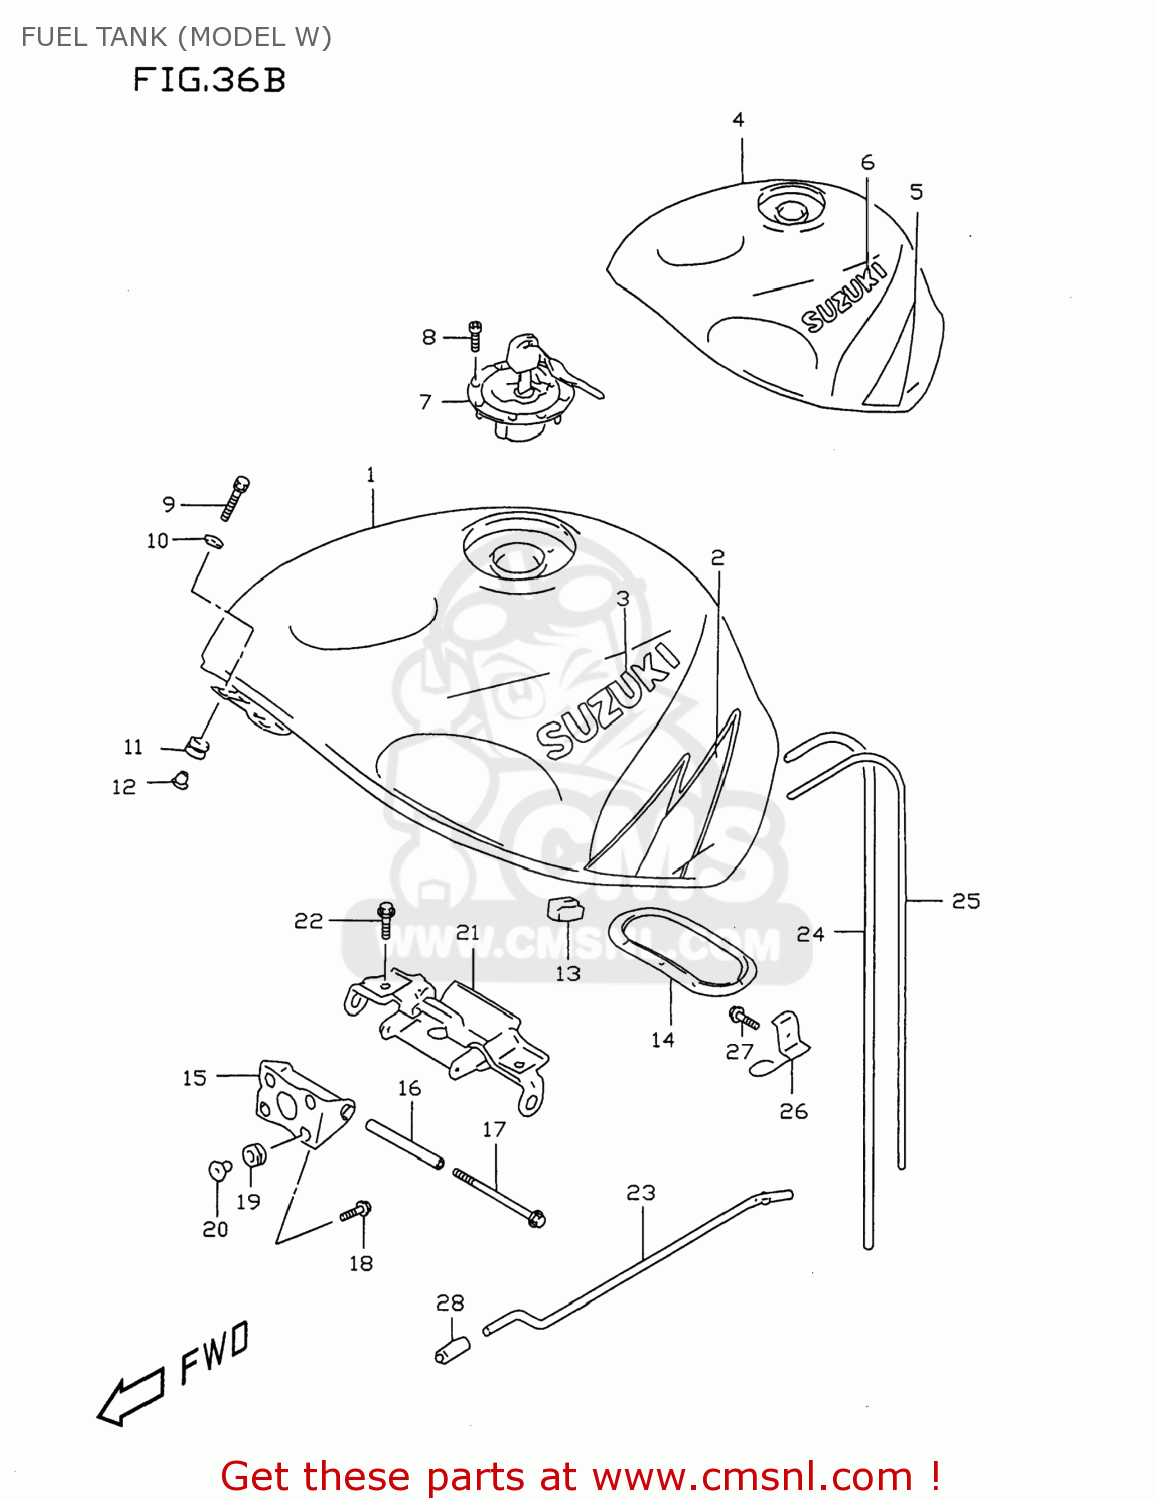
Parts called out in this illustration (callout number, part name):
1	TANK ASSEMBLY,FUEL
2	TAPE SET,FUEL TANK
3	EMBLEM,FUEL TANK
4	TANK ASSY,FUEL
5	TAPE SET,FUEL TANK
6	EMBLEM,FUEL TANK
7	CAP SET,FUEL TANK
8	BOLT(5X20)
9	SCREW(6X25)
10	WASHER(6.5X18X1.6)
11	CUSHION
12	WASHER
13	CUSHION,FUEL TANK SIDE
14	PACKING SET,FUEL PUMP (NAS)
14A	BOLT,FUEL PUMP
15	BRACKET COMP,FUEL TANK
16	SPACER,FUEL TANK RR
17	BOLT
18	BOLT 6X20,WITH PLAIN WASHER
19	CUSHION
20	WASHER
21	BRACKET,FUEL TANK NO.2
22	BOLT
23	STAY,FUEL TANK
24	HOSE(5X8.2X600)
25	HOSE(7X10.2X600)
26	GUIDE COMP,DRAIN HOSE
27	BOLT
28	CAP,OD:11
